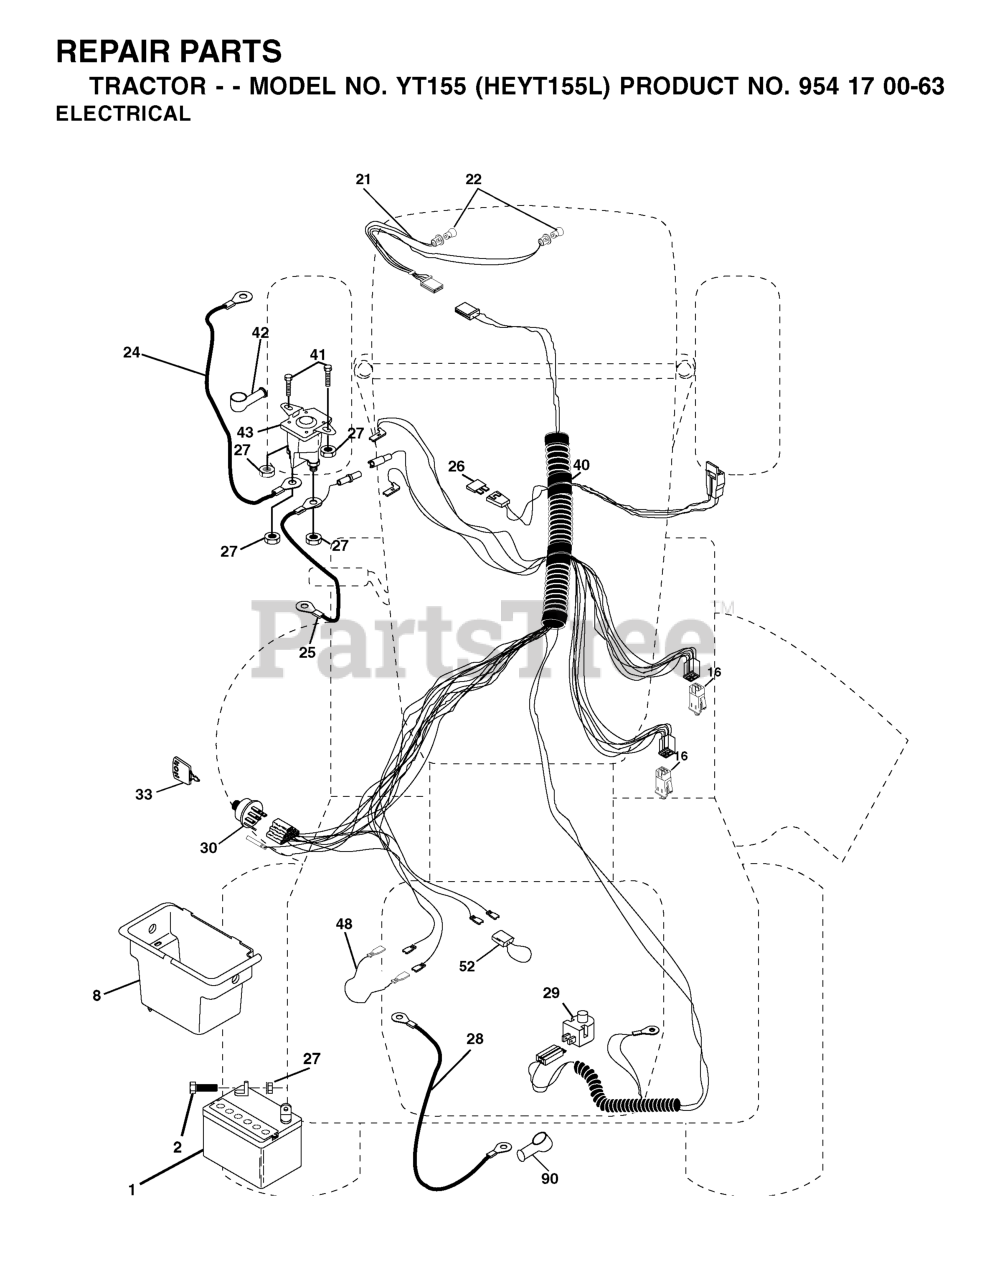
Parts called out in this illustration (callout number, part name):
1	Battery 12 Volt 25 Amp
2	BOLT.HEX.1/4.X.3/4.DICHROMATE
8	BOX.BATTERY.FENDER
16	SWITCH INTERLOOK PUSH-IN
24	BATTERY CABLE GT
25	CABLE BATTERY
26	FUSE 20AMP
27	NUT
28	CABLE T
29	RP.SWITCH.PLUNGER.NC.GRAY
30	IGNITION SWITCH
33	KEY MLD GEN DELTA
40	HARNESS.IGNITION
41	BOLT
42	TERMINAL COVER
43	SOLENOID
48	ADAPTER.AMMETER
52	WIRE PROTECTION LOOP
90	COVER TERMINAL
